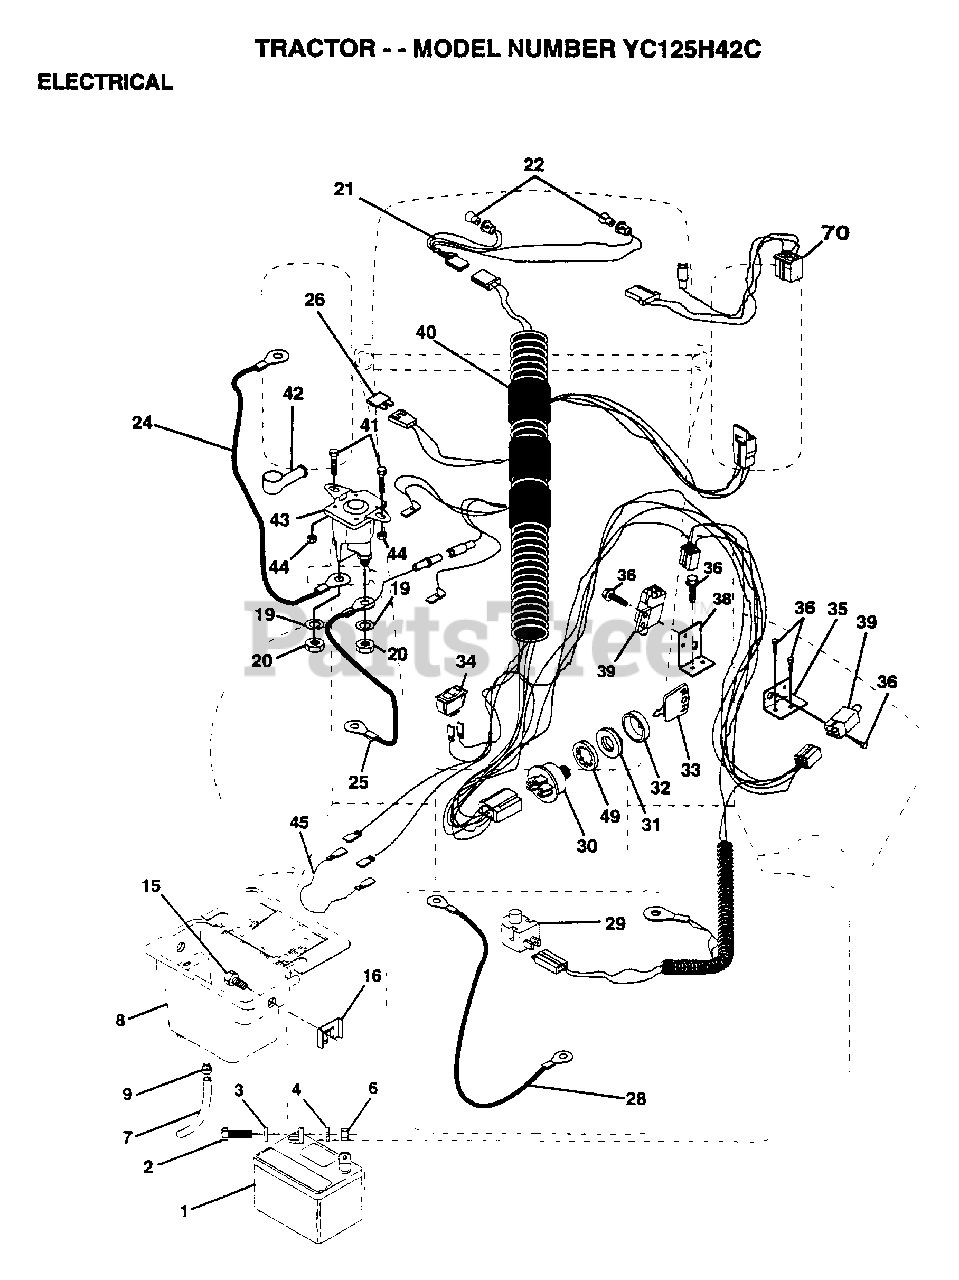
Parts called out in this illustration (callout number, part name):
2	BOLT LT
3	WASHER
4	LOCKWASHER
7	TUBE T
9	HOSE CLAMP T
15	SCREW.CAP.HEX.NYL
16	NUT.CLIP.FASTNER
20	NUT
21	"HARNESS,LIGHT SOC"
22	HEADLAMP BULB
24	"CABLE T, BATTERY"
25	CABLE.BTRY.6GA.RD
26	FUSE HYT
28	CABLE T
29	SWITCH SEAT
32	COVER KEY SWITCH
33	KEY MLD GEN DELTA
34	SWITCH LT
35	BRACKET LT
36	SCREW
38	BRACKET SWITCH IN
39	SWITCH INTERLOCKT
40	HARNESS.IGN.DASH.
41	BOLT.HX.1/4-20
44	NUT
45	ADAPTER AMMETER
49	LOCKWASHER
70	HARNESS ENG DUAL
